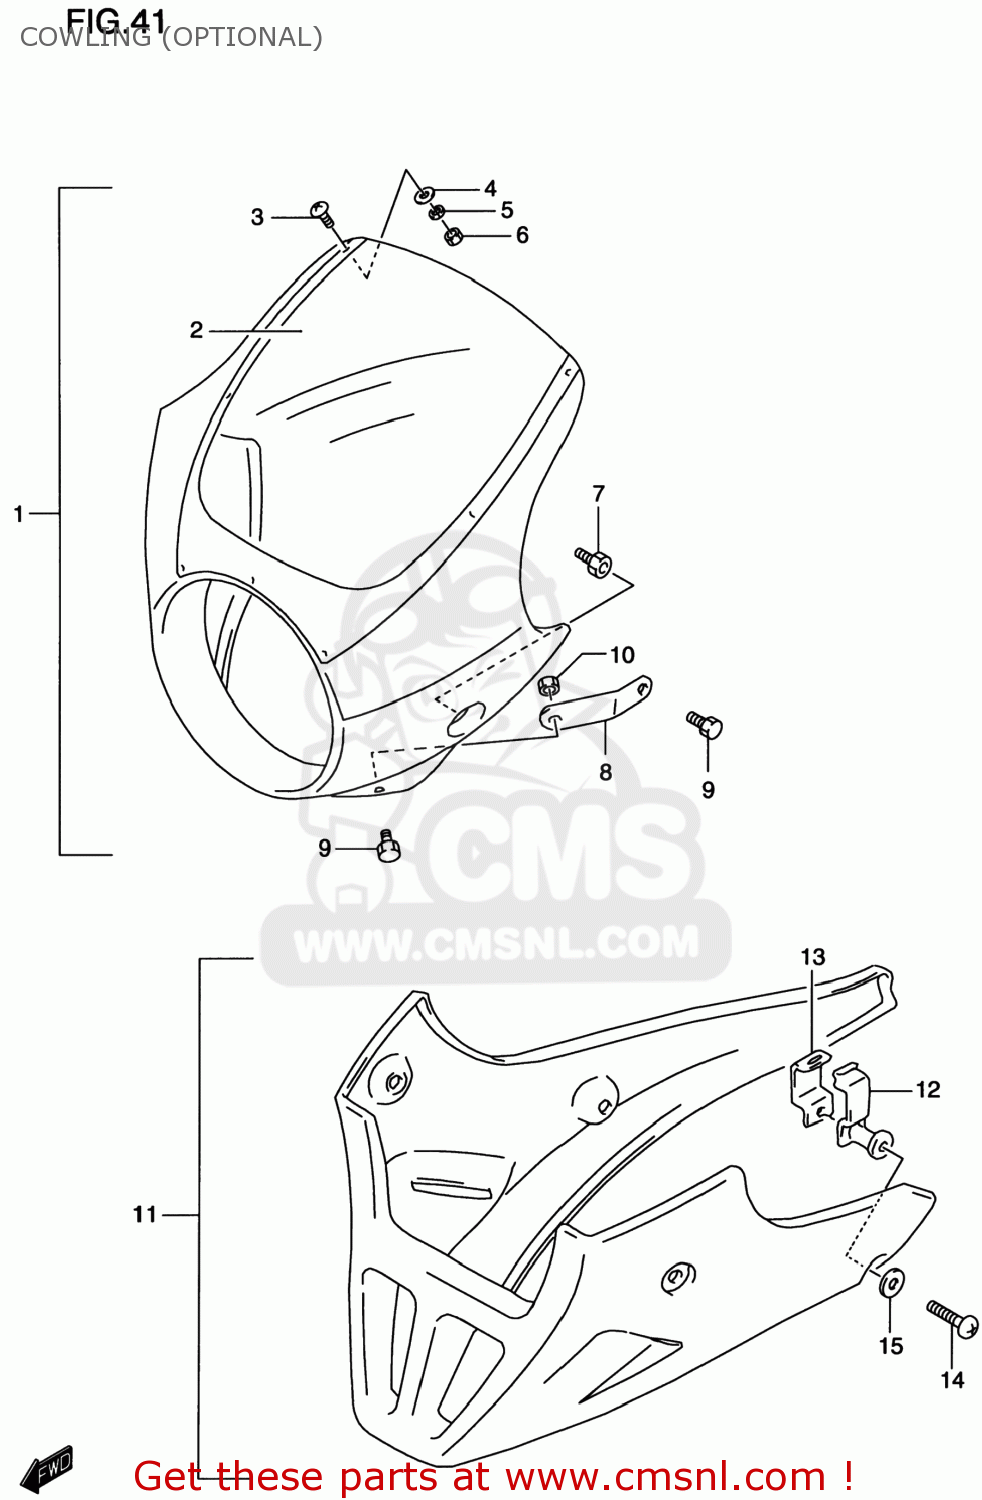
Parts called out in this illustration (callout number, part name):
1	COVER SET,UPPER COWLING
2	SCREEN,COWLING
3	SCREW
4	WASHER
5	WASHER,LOCK
6	NUT
7	BOLT,UPR COWLING HEADLAMP
8	BRACE,UPR COWLING
9	BOLT
10	NUT 6MM
11	COVER SET,UNDER COWLING
12	BRACKET,UNDER COWLING OUTER
13	BRACKET,UNDER COWLING INNER
14	SCREW
15	WASHER(6.5X18X1.6)
